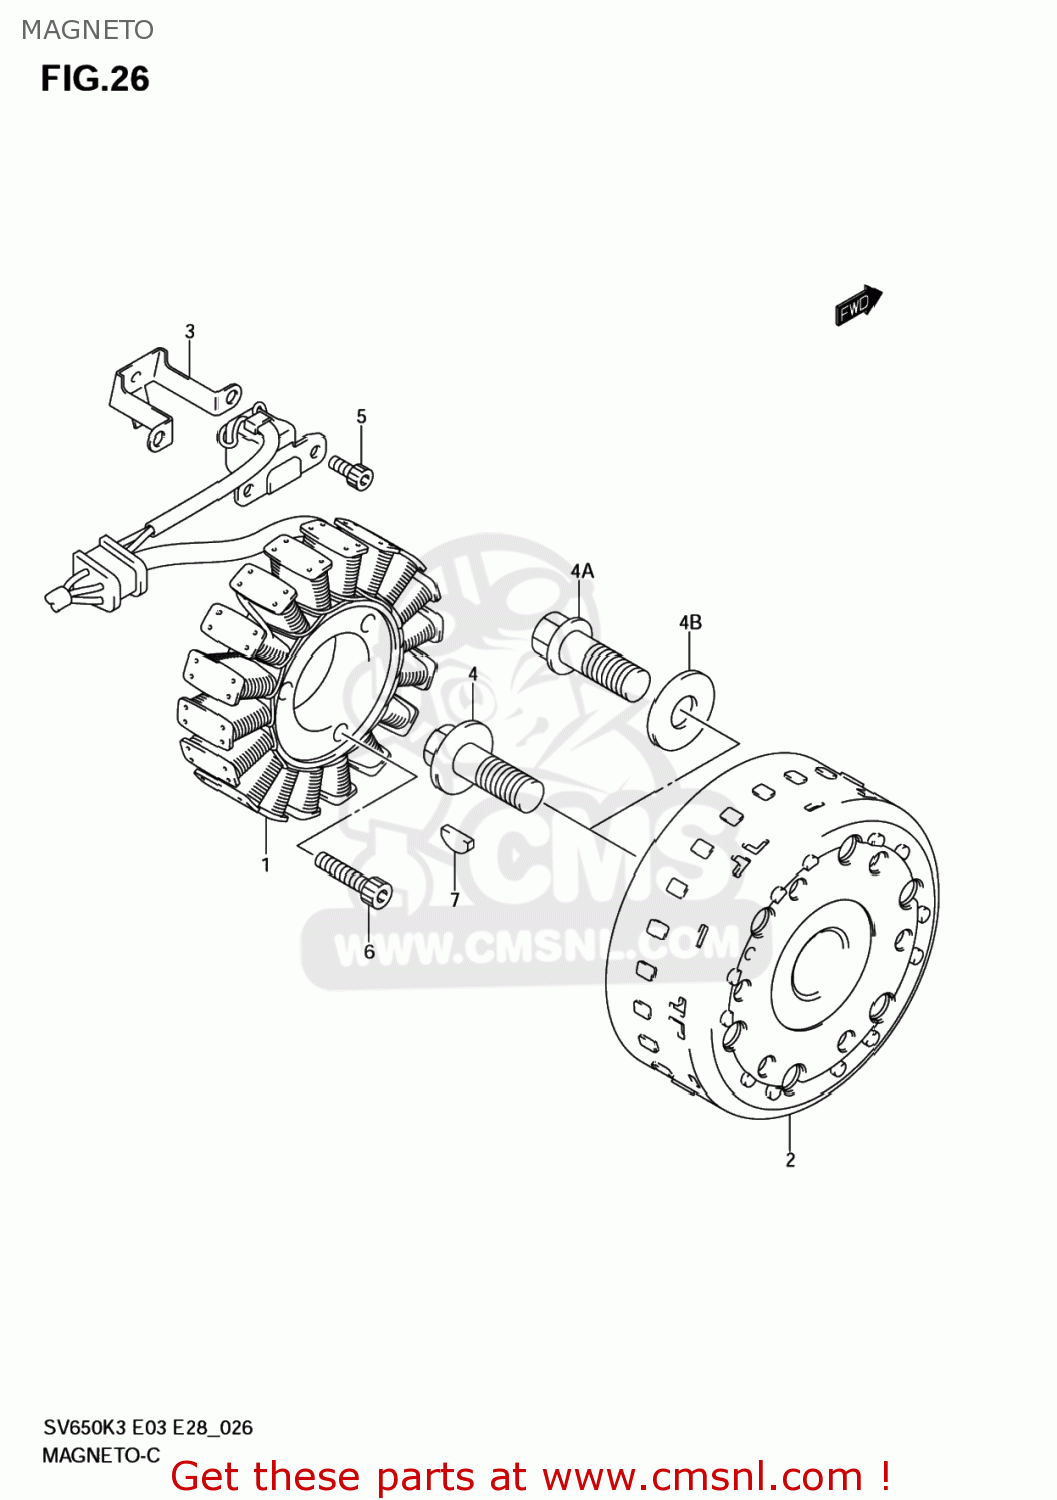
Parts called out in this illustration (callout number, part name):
1	STATOR ASSY
2	ROTOR ASSY
3	CLAMP,MAGNETO LEAD
4	BOLT,MAGNETO ROTOR
4A	BOLT(12X40)
4B	WASHER(12X30X3)
5	BOLT
6	BOLT
7	KEY
